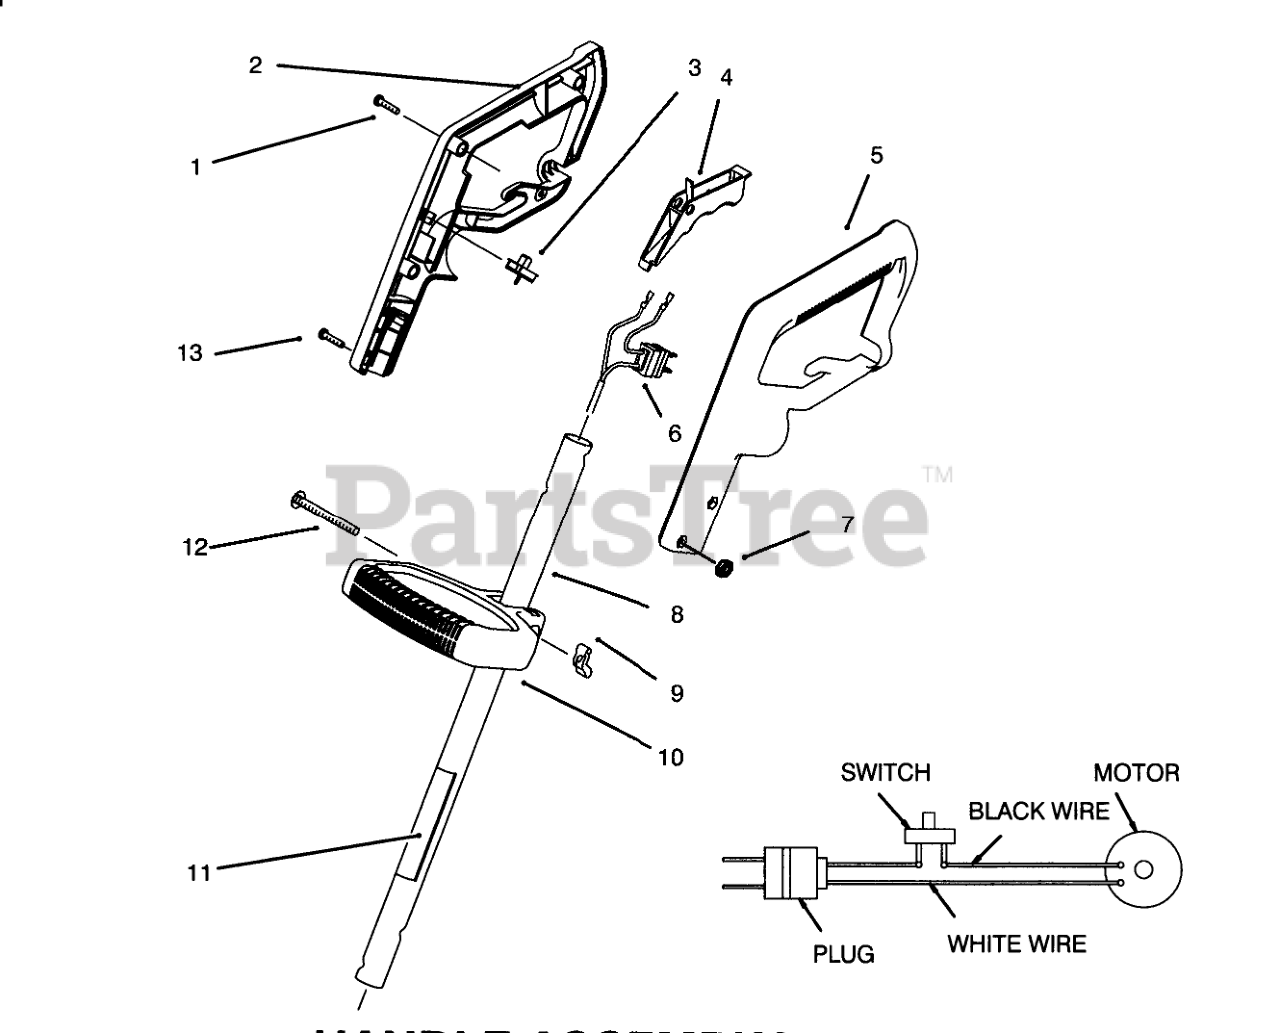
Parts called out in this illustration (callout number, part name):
1	Screw
2	HAND GRIP R.H.
3	SWITCH
4	TRIGGER
5	HAND GRIP L.H.
6	WIRING HARNESS
7	NUT-HEX
8	Tube Assembly (Incl. Ref. #11)
9	1/4"-20 STAMP WNG NUT
10	MID HANDLE
11	Decal-Safety
12	SCREW-CARR.25-20 X 2.50
13	SCREW-PPH
